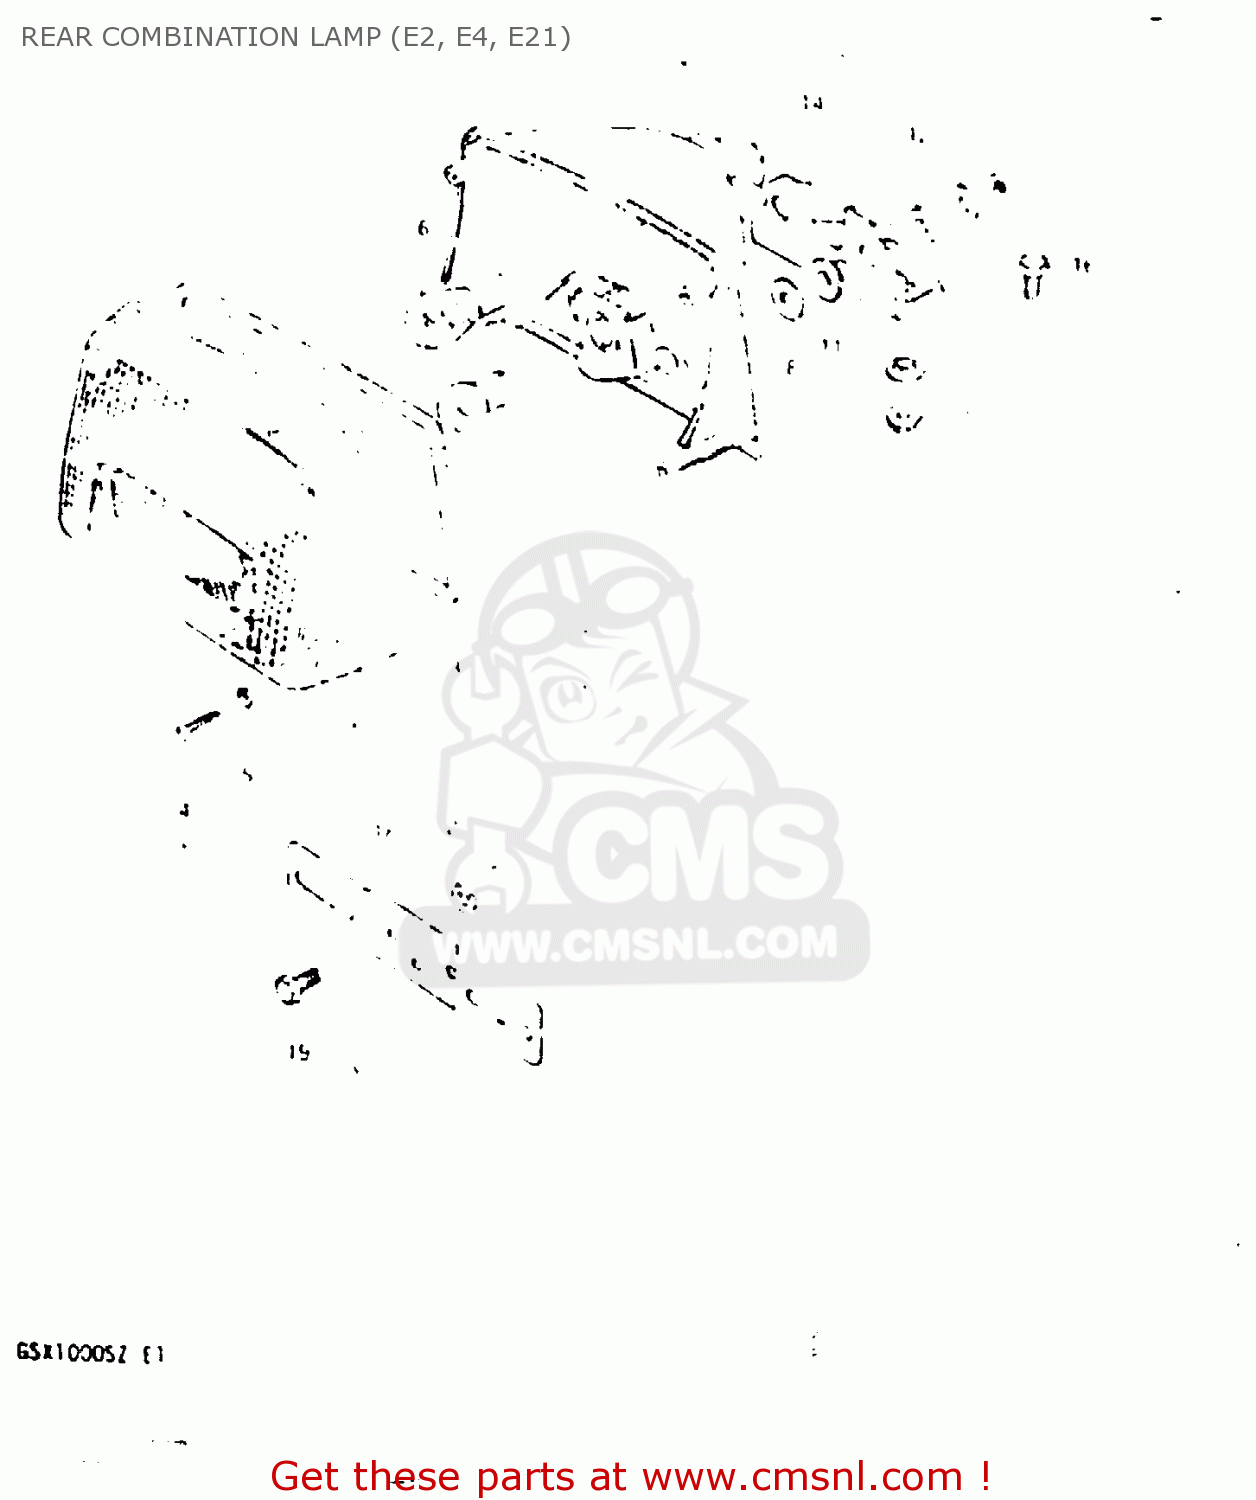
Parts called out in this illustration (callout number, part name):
1	LAMP ASSY, TAIL
2	LENS
3	GASKET (NAS)
4	SCREW,REAR COMBINATION LAMP
5	GASKET (NAS)
6	BULB 12V21/5W
7	BULB
8	WASHER
9	WASHER(6,5X22X1.6)
10	SPACER(6.1X9X7.5)
11	CUSHION
12	CUSHION
13	NUT 6MM
14	BRACKET,RR COMBINATION LAMP
15	WASHER
16	BOLT, UPPER
17	NUT 6MM
18	PLATE,RR LICENSE
19	BOLT
20	NUT
21	LOCK WASHER
